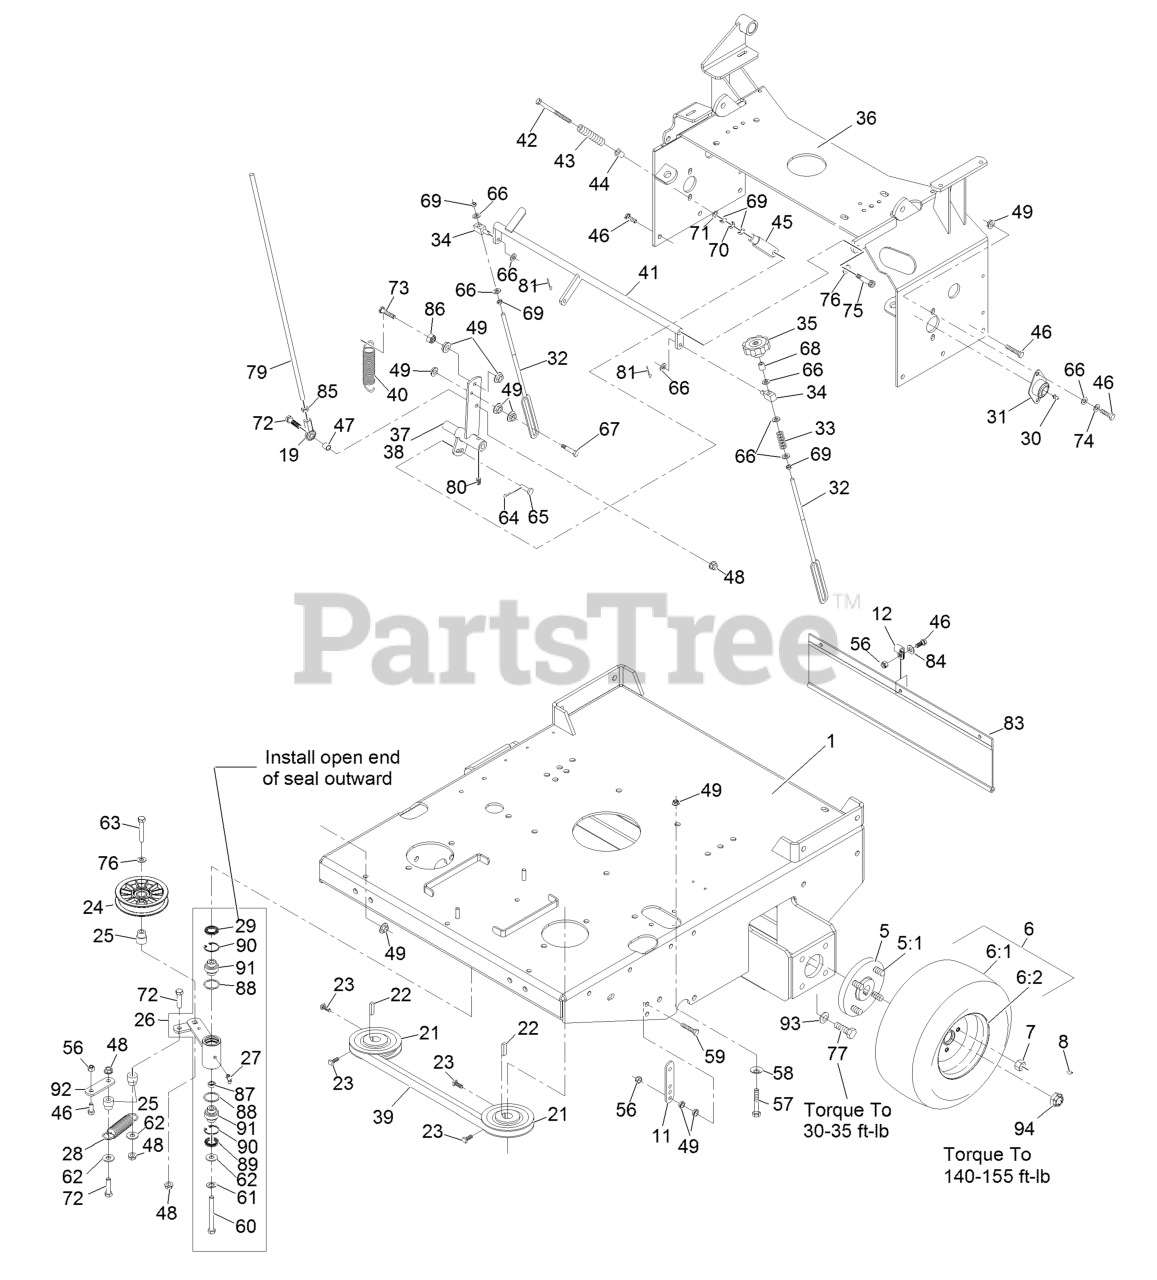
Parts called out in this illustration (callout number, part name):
1	KIT, TTX ENG DECK W/DECAL
5	WHEEL HUB ASM
5:1	STUD-WHEEL
6	ASM, DRIVE TIRE
7	NUT-LUG
8	KEY-WOODRUFF
11	TAB-SPRING, EXTENSION
12	CLIP-LOOM
19	JOINT-BALL END, LH
21	SHEAVE ASM
23	SCREW-SET, SQH
24	PULLEY-IDLER, FLAT
25	BUSHING-IDLER
26	KIT,IDLER ARM W/BRGS.
27	FITTING-GREASE, 90 DEG
28	SPRING-EXTENSION
29	SEAL-LIP, SINGLE
30	FITTING-GREASE
31	BEARING-FLANGE, SIDE
32	LINK,SPEED CONTROL
33	SPRING-COMPRESSION
35	KNOB-TRACKING
36	WLD,FUEL TANK SUPPORT TT
37	WLD,LH CONTROL ARM
39	BELT,COG A-59.5
40	SPRING-EXTENSION
41	WLD,CRANK SPEED CNTRL
42	BOLT-RETURN, NEUTRAL
43	SPRING,COMPRESSION (NEUT)
44	BUSHING-FLANGED
45	YOKE-ADJUSTABLE
46	SCREW-HH
47	TUBE,PUMP LINK SPACER
48	NUT-HHF, WHIZ
56	NUT-LOCK, NI
57	SCREW-HH
58	WASHER-SPRING
59	BOLT-TAP, HH
60	SCREW-HH
61	WASHER-LOCK
62	WASHER-FLAT
63	SCREW-HH
64	PIN-COTTER
65	PIN-CLEVIS
66	WASHER-PLAIN
67	SCREW-HH
69	NUT-HEX
70	NUT-JAM
71	WASHER-FLAT
72	SCREW-HH
73	SCREW-HH, SPECIAL
74	WASHER-LOCK
75	SCREW-HSH
76	WASHER-FLAT
77	SCREW-HH
79	LINK,DRIVE (PLTD)
80	SCREW-SET
81	PIN-COTTER
83	SHIELD,DRAG
84	WASHER-FLAT
85	NUT-HEX JAM, LH
86	NUT-JAM
89	SEAL-LIP, DOUBLE
90	RING-SNAP
91	BEARING-SPHERICAL
92	ARM-LIFT, DECK
93	WASHER-BELLEVILLE
94	NUT-LOCK
